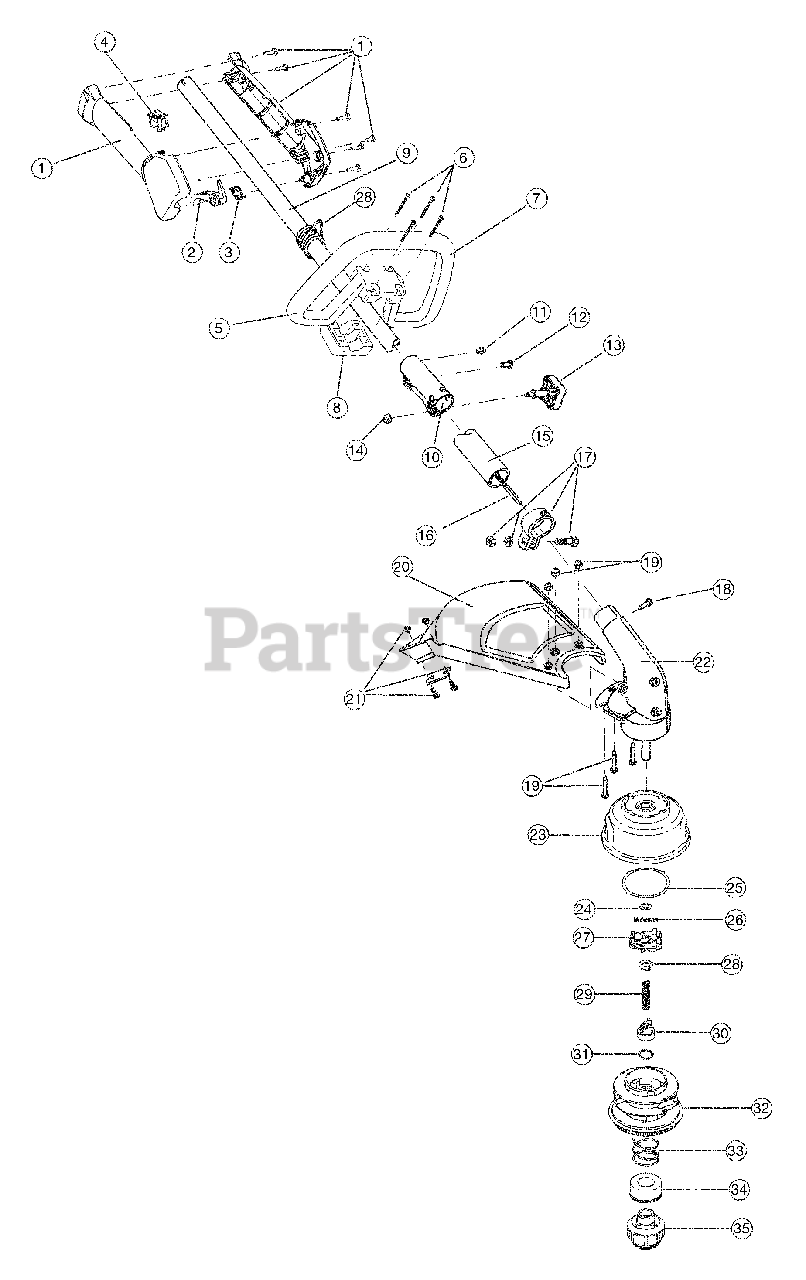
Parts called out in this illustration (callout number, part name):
1	Throttle Housing Assembly
2	Throttle Trigger
3	Throttle Trigger Spring
4	Switch Assembly
5	Deluxe D-Handle Assembly
6	Handle Mount Hardware
7	Deluxe D-Handle
8	Bottom Clamp
9	Upper Drive Shaft Housing Assembly
10	Split Boom Coupler
13	Adjustment Knob
14	Knob Retaining Nut
15	Lower Drive Shaft Housing Assembly
16	Lower Flexible Drive Shaft
17	Lower Clamp Assembly
18	Anti-Rotation Screw
19	Shield Mounting Hardware
20	Shield and Blade Assembly
21	Blade Assembly
22	Gearbox Assembly
23	Outer Spool Assembly
24	Retaining Ring
25	Thrust Washer
26	Small Spring
32	Inner Reel
33	Large Spring
35	Bump Head Knob Assembly
